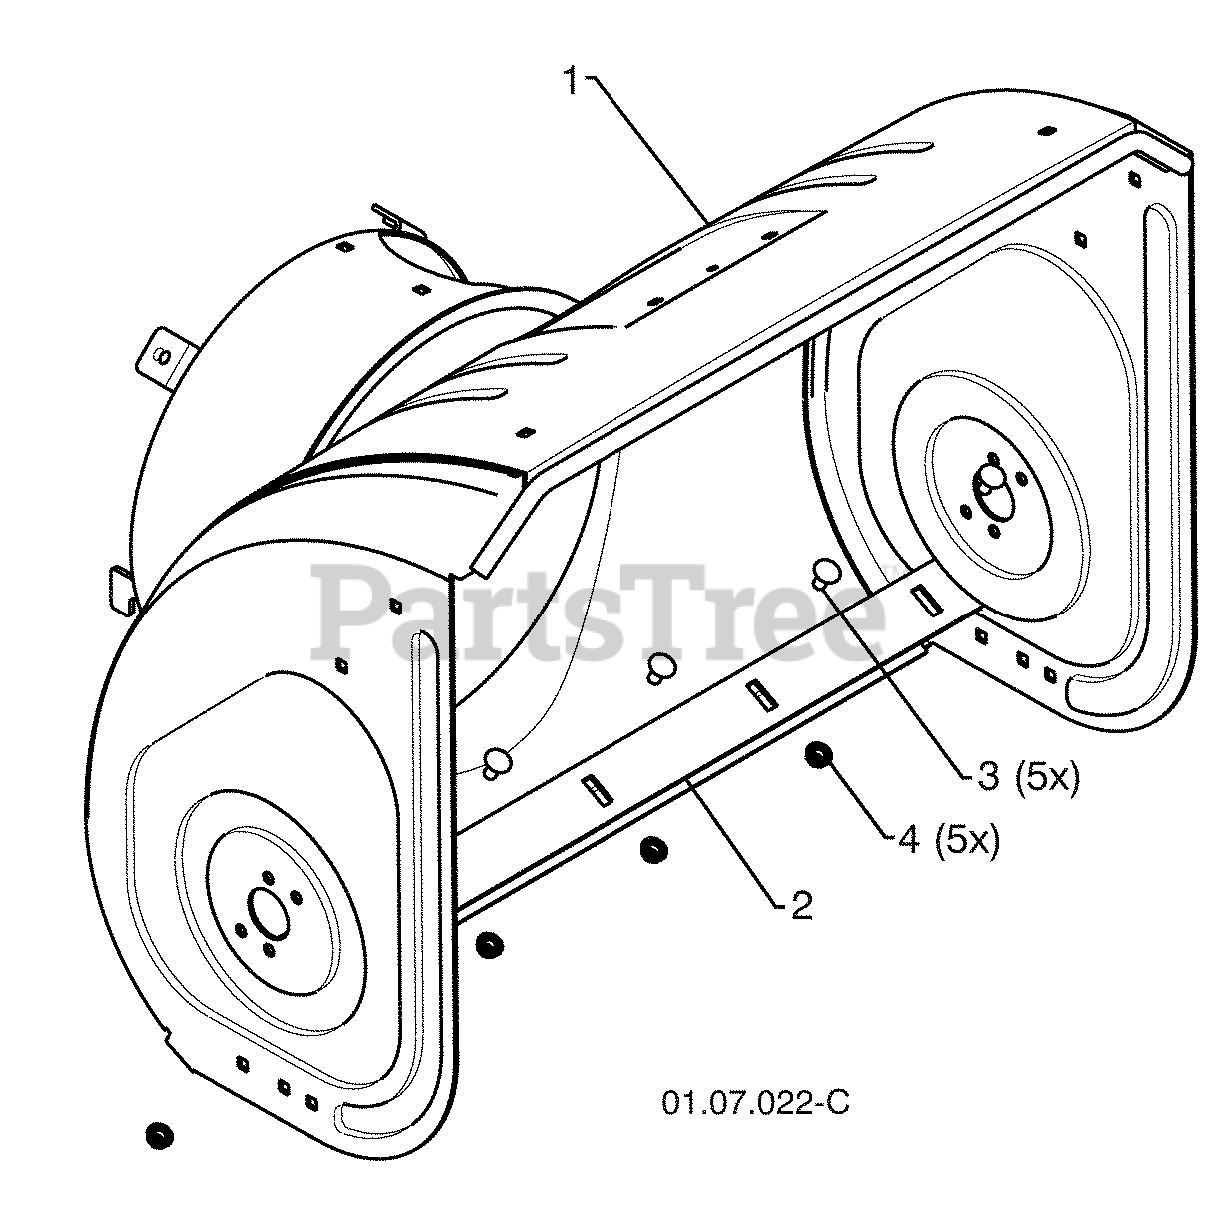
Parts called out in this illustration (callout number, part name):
1	HOUSING.AUG.WELDMENT.27.ORANGE
2	BAR, SCRAPER
3	BOLT
4	NUT.FLANGE.5/16
